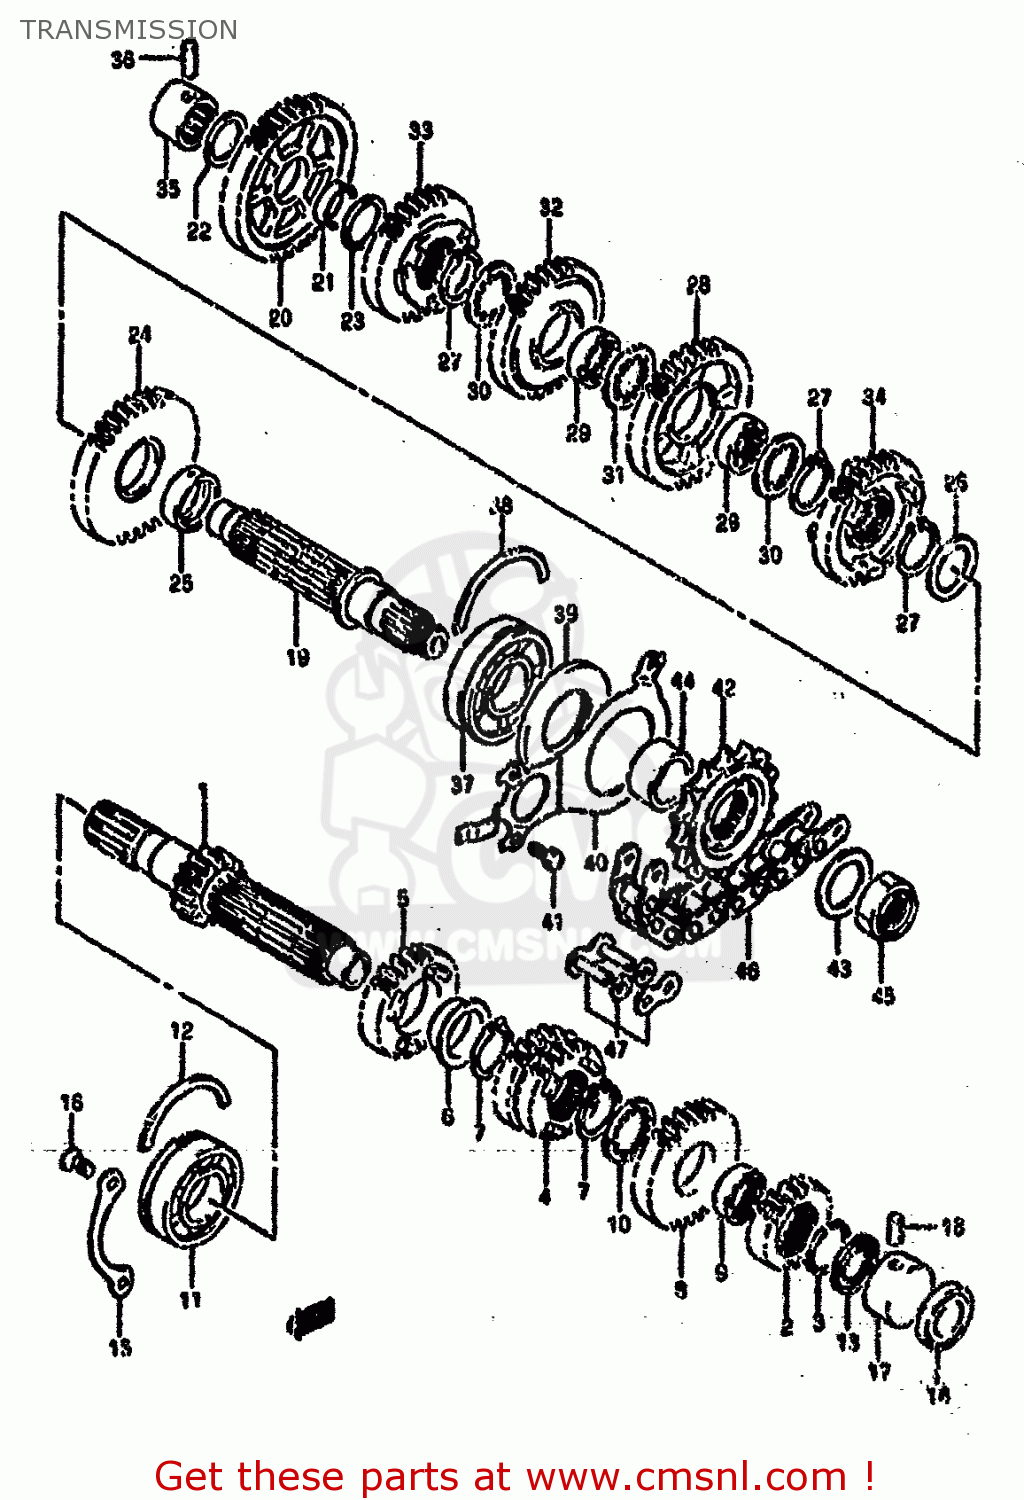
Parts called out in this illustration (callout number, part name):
1	COUNTERSHAFT (NT:15)
2	GEAR,2ND DRIVE (NT:16)
3	CIRCLIP
4	GEAR,3&4TH DRIVE CA(NT:18/24)
5	GEAR,5TH DRIVE B(NT:25)
6	BUSH(28X32X2)
7	CIRCLIP
8	GEAR,6TH DRIVE (NT:22)
9	BUSHING,SIXTH DRIVE GEAR
10	WASHER,LOCK
11	BEARING(25X62X17)
12	C-RING
13	SEAL,OIL(20X31.2X2.7)
14	CAP,COUNTER SHAFT,L
15	RETAINER,CNTR SHAFT BEARING
16	SCREW ,6X16
17	BEARING(20X34X17.5)
18	PIN
19	SHAFT,DRIVE
20	GEAR,1ST DRIVEN (NT:36)
21	BUSH(22X26X9)
22	WASHER
23	WASHER
24	GEAR,2ND DRIVEN (NT:31)
25	BUSH(28X32X9.5)
26	WASHER, THRUST
27	CIRCLIP
28	GEAR 3RD DRIVEN B(NT:36)
29	BUSH,3RD DRIVEN GEAR
30	WASHER,LOCK
31	WASHER,LOCK
32	GEAR,4TH DRIVEN (NT:29)
33	GEAR,5TH DRIVEN (NT:33)
34	GEAR,6TH DRIVEN B(NT:27)
35	BEARING(20X34X20)
36	PIN
37	BEARING(28X70X18)
38	C RING
39	SEAL,OIL(34.8X70X6)
40	RETAINER,DRIVE SHAFT OIL SEAL
41	BOLT
42	SPROCKET,ENGINE
43	WASHER,THRUST
44	SPACER(25X36X17.7)
45	NUT
46	CHAIN ASSEMBLY RK50GSVZ1.1
47	JOINT SET,DRIVE CHAIN
